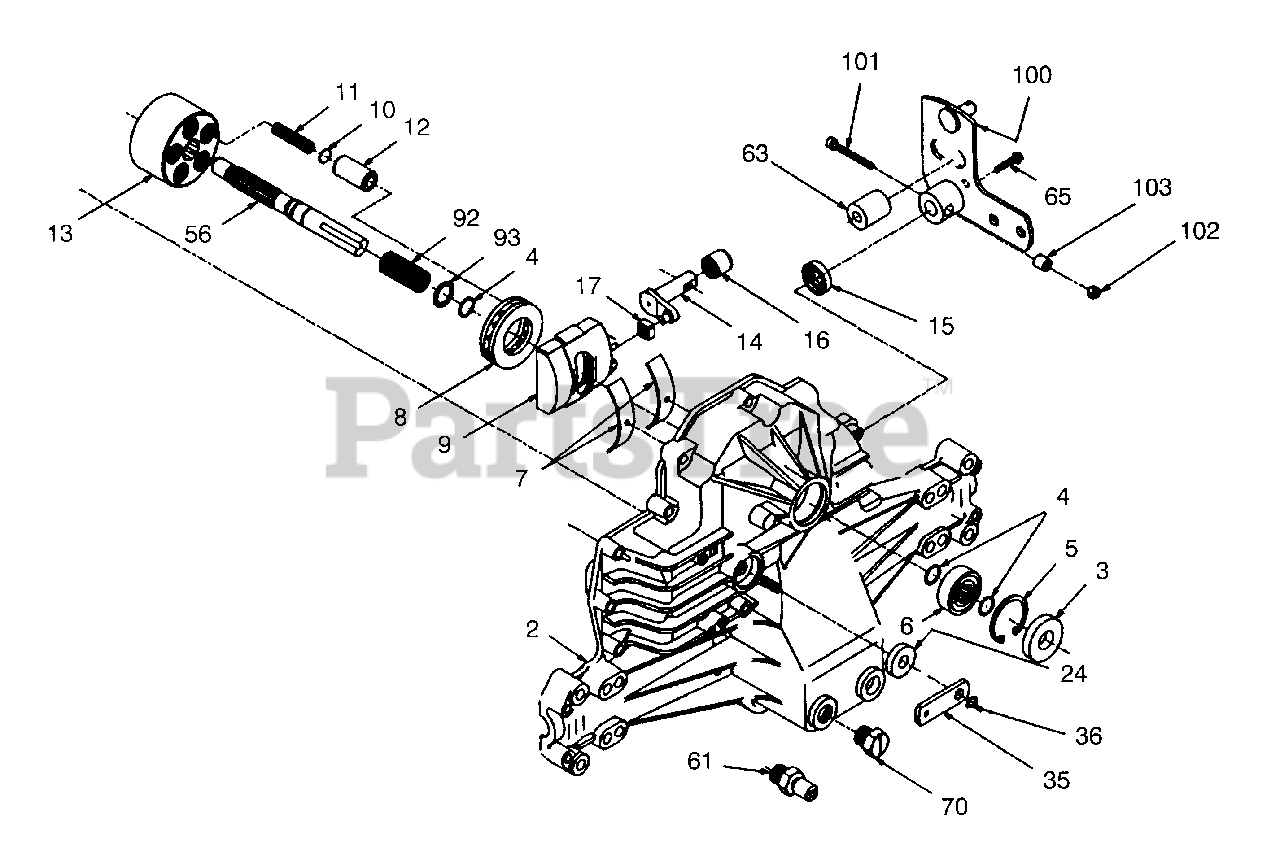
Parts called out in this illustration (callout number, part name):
2	Housing-Upper
3	Seal-Lip
4	Ring-Wire Retaining
5	Ring-Retaining
6	Bearing-Shaft Ball
7	Bearing-Cradle
8	Bearing-Thrust
9	Swashplate-Variable
10	Washer-Piston Thrust
11	Spring-Piston
12	Piston
13	Block Cylinder (Motor)
14	Arm-Trunnion
15	Seal-Lip
16	Bearing-Trunnion Journal
17	Guide-Slot
24	Seal-Lip
26	Plate-Bypass
35	Arm-Bypass
36	Ring-Retaining
56	Shaft-Input
61	Breather Ass'y
63	Spacer
65	Bolt
70	Plug-Plastic
92	Spring-Block
93	Washer-Block Thrust
100	Control Arm Ass'y
101	Socket Head Cap Screw
